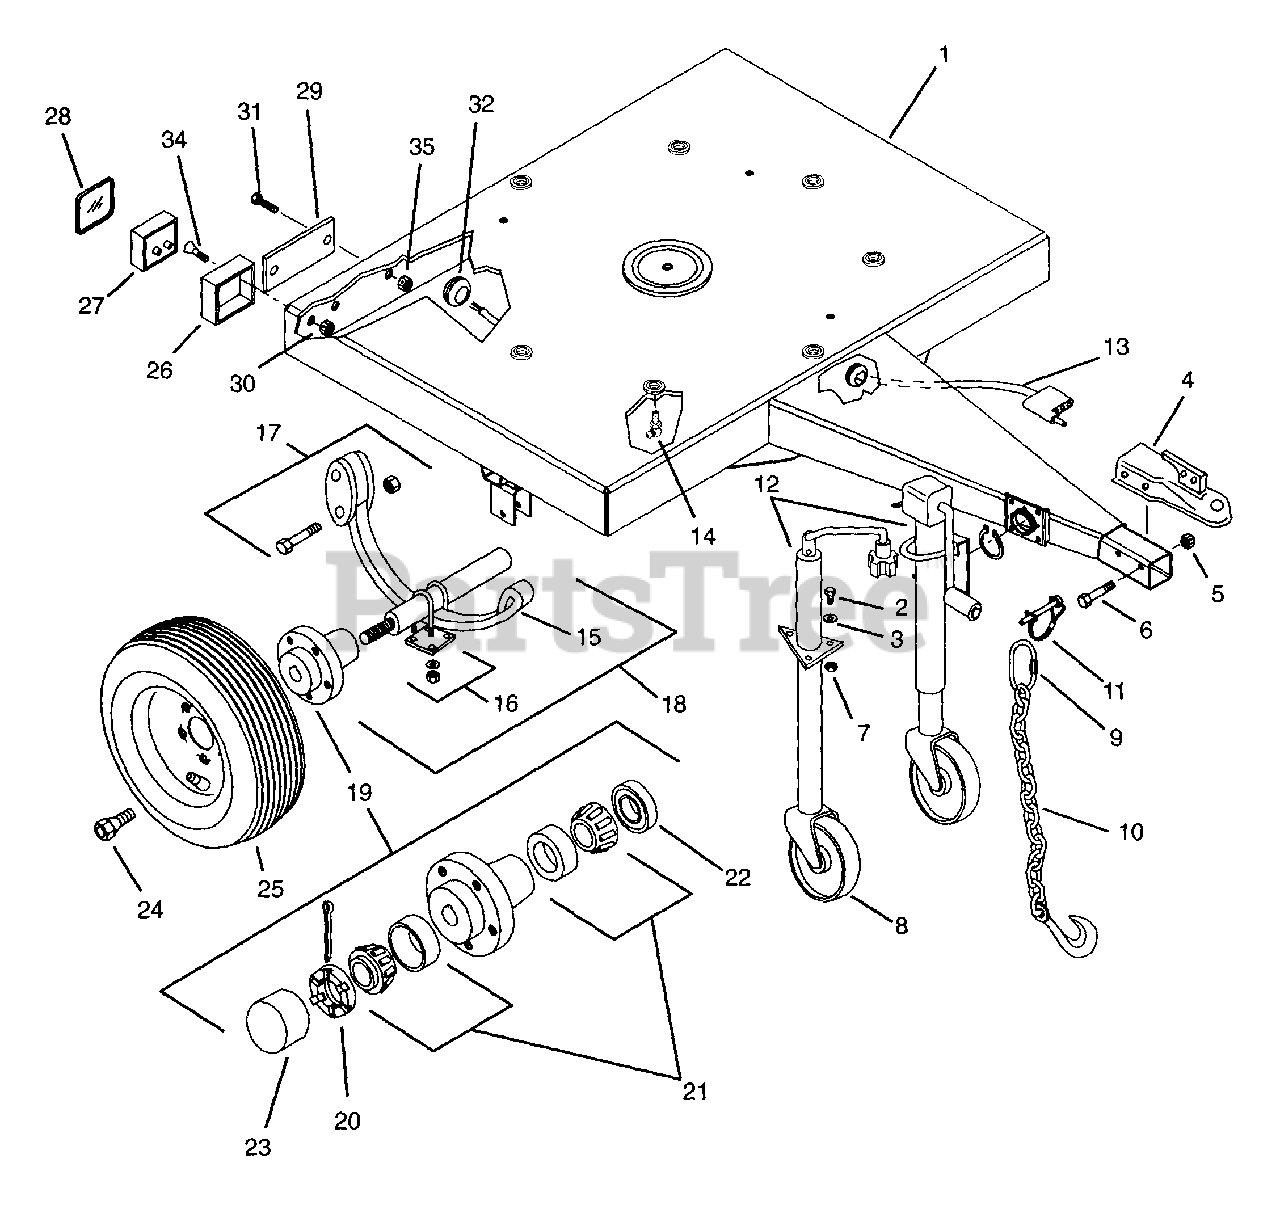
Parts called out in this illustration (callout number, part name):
1	Trailer 310
1	Trailer 350
2	Bolt-Hex .44-14 x 1.25-Grade 5
3	Washer-Flat-Steel .438 x 1.0 x .083
4	Coupler 2" Ball Type
5	Nut-Locking Crown .50-13
6	Bolt-Hex .50-13 x 3.75
7	Nut-Locking-Crown .437-14
8	Swivel Wheel
9	Quick Link 5/16
10	Safety Chain
11	Quick Latch Pin Jack Wheel
12	Jack Assembly
13	Wire Harness
14	Hydraulic Drive Fitting
15	Axle Spring
16	U-Bolt, Kit, Dexter Axle 2000#
17	Hardware
18	Axle, Complete-Less Tire & Wheel
19	Axle Hub
20	Nut Slotted 1.0-14
21	Kit, Bearing
24	Lug .50-20 x .75 x 1.62 Plated
25	Tire/Wheel Assembly
25	Tire and Wheel Assembly
26	Left Taillight Weldment
26	Right Taillight Weldment
27	Taillight, Left Hand
27	Taillight, Right Hand
28	Lens, Tail Light
29	Reflector
30	Nut-Locking-Center .25-20
31	Screw-Machine 10-24 x 1.00 HWH
32	Grommet .188 x 1.38
33	Grommet .75 x 1.06 x 1.38
34	Screw-Machine-Flat .25 x .75
35	Nut-Locking-Nylon 10-24 w/Insert
